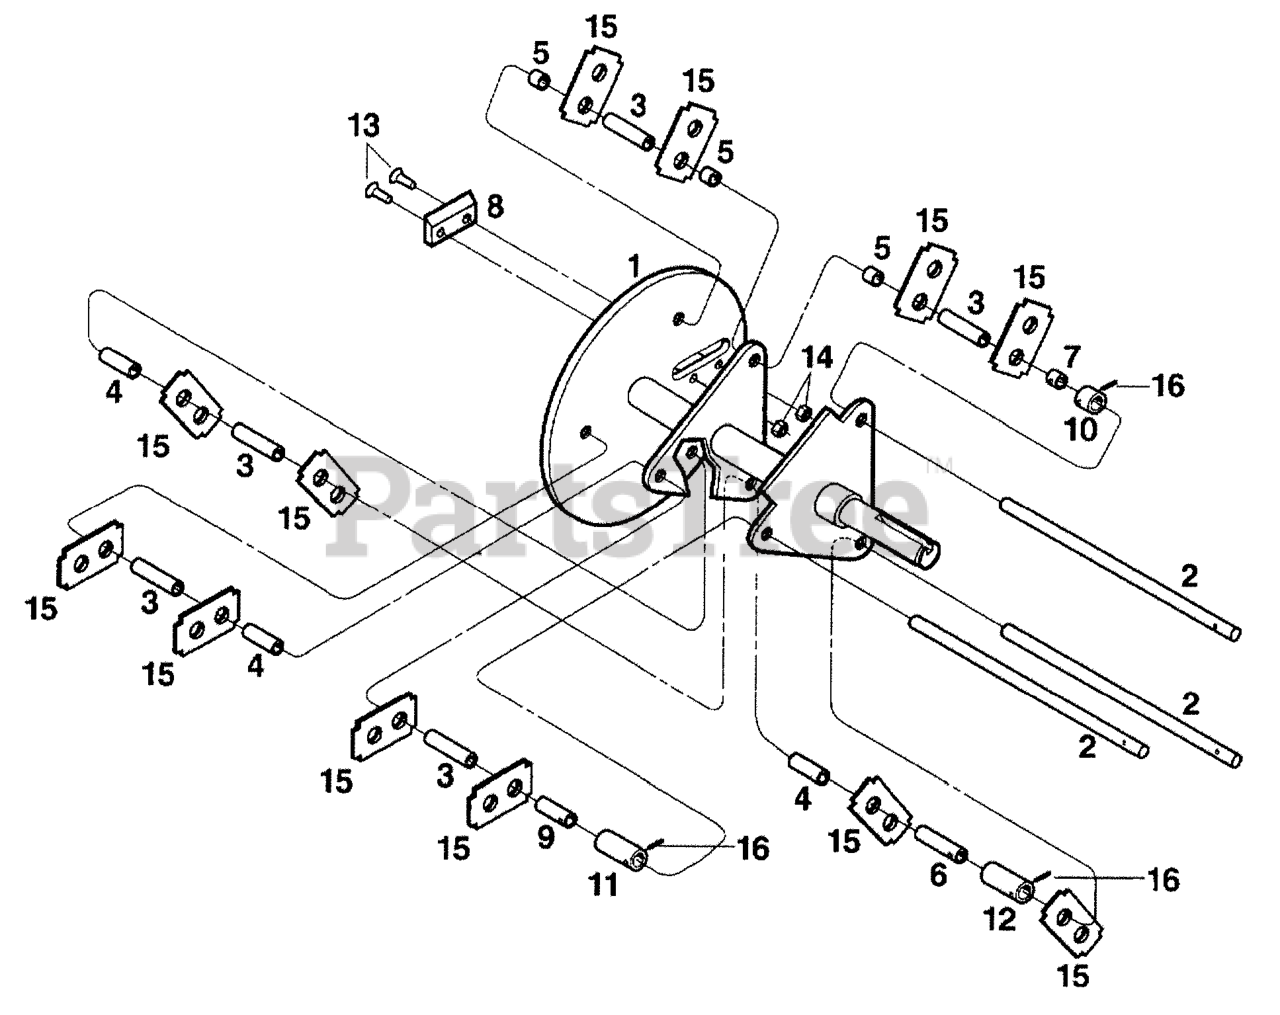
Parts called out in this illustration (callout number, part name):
1	Weldment, Cylinder
2	Pin, Cylinder
3	Spacer, Long
4	Spacer, Medium 2"
5	Spacer, Short 11/16"
6	Spacer, Long Locking 2"
7	Spacer, Short Locking 11/16"
8	Kit, Chipper Blade
9	Spacer, Medium Locking 1-5/16"
10	Sleeve, Short Outer 1/2"
11	Sleeve, Medium Outer 1-1/8"
12	Sleeve, Long Outer 1-3/4"
13	Screw, Socket Head 1/4-20 x 1"
14	Locknut, Hex 1/4-20
15	Blade, Shredder
16	Pin, Roll 3/16 x 3/4
17	Kit, Spacer
